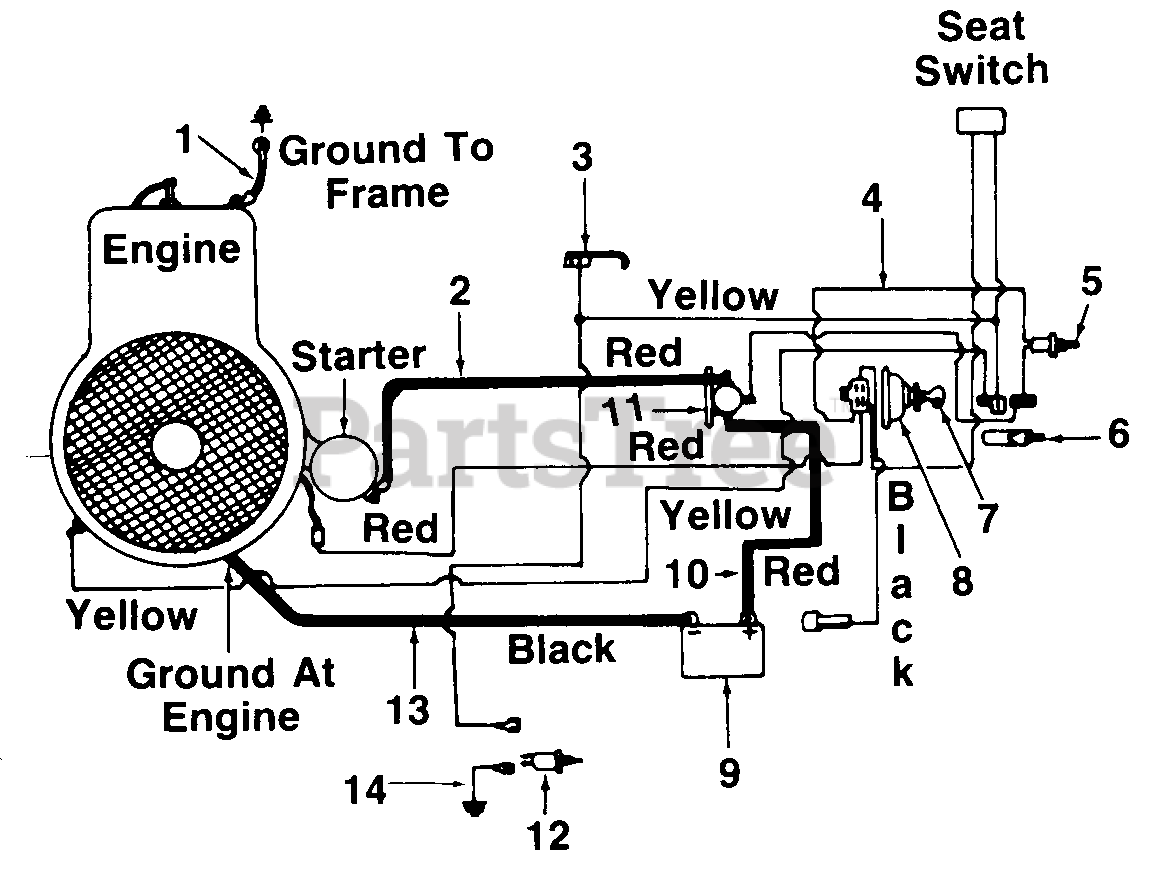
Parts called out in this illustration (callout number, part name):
1	Elec. Wire 8 Ga. x 9.0" Lg.
3	Spring Switch-Reverse
4	Wire Harness
5	Safety Switch-Black N.O.
6	Safety Switch
7	Ignition Key
8	Ignition Switch
9	Battery 12V
10	Elec. Wire Red w/Boot
11	Solenoid
12	Safety Switch Red N.C.
13	Elec. Wire 8 Ga. x 9.0" Lg.
